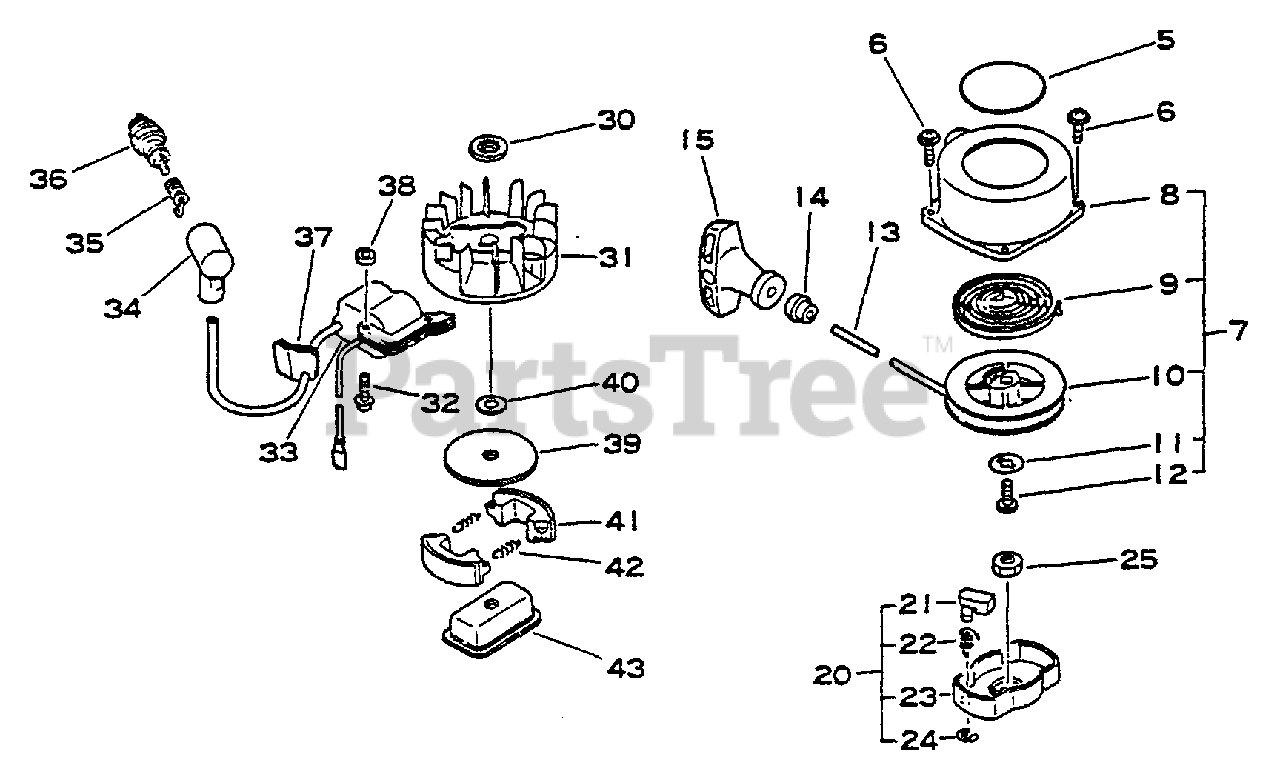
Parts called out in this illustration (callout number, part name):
5	LABEL, ECHO
6	SCREW 4×14
7	STARTER ASSY
8	CASE, RECOIL STARTER
9	SPRING, RECOIL
10	REEL, ROPE
11	WASHER
13	ROPE, STARTER
14	GUIDE, ROPE
15	GRIP, STARTER
20	STARTER PAWL ASSY
21	PAWL, STARTER
22	SPRING, RETURN
23	CATCHER, PAWL
24	RING, RETAINING - 6
25	NUT M8×1
30	WASHER
31	FLYWHEEL
32	SCREW 4×22
33	COIL, IGNITION
34	CAP, SPARK PLUG
35	TERMINAL, SPARK PLUG CAP
36	SPARK PLUG - BM6A
39	PLATE, CLUTCH
41	SHOE, CLUTCH
42	SPRING, CLUTCH
43	BOSS, CLUTCH
